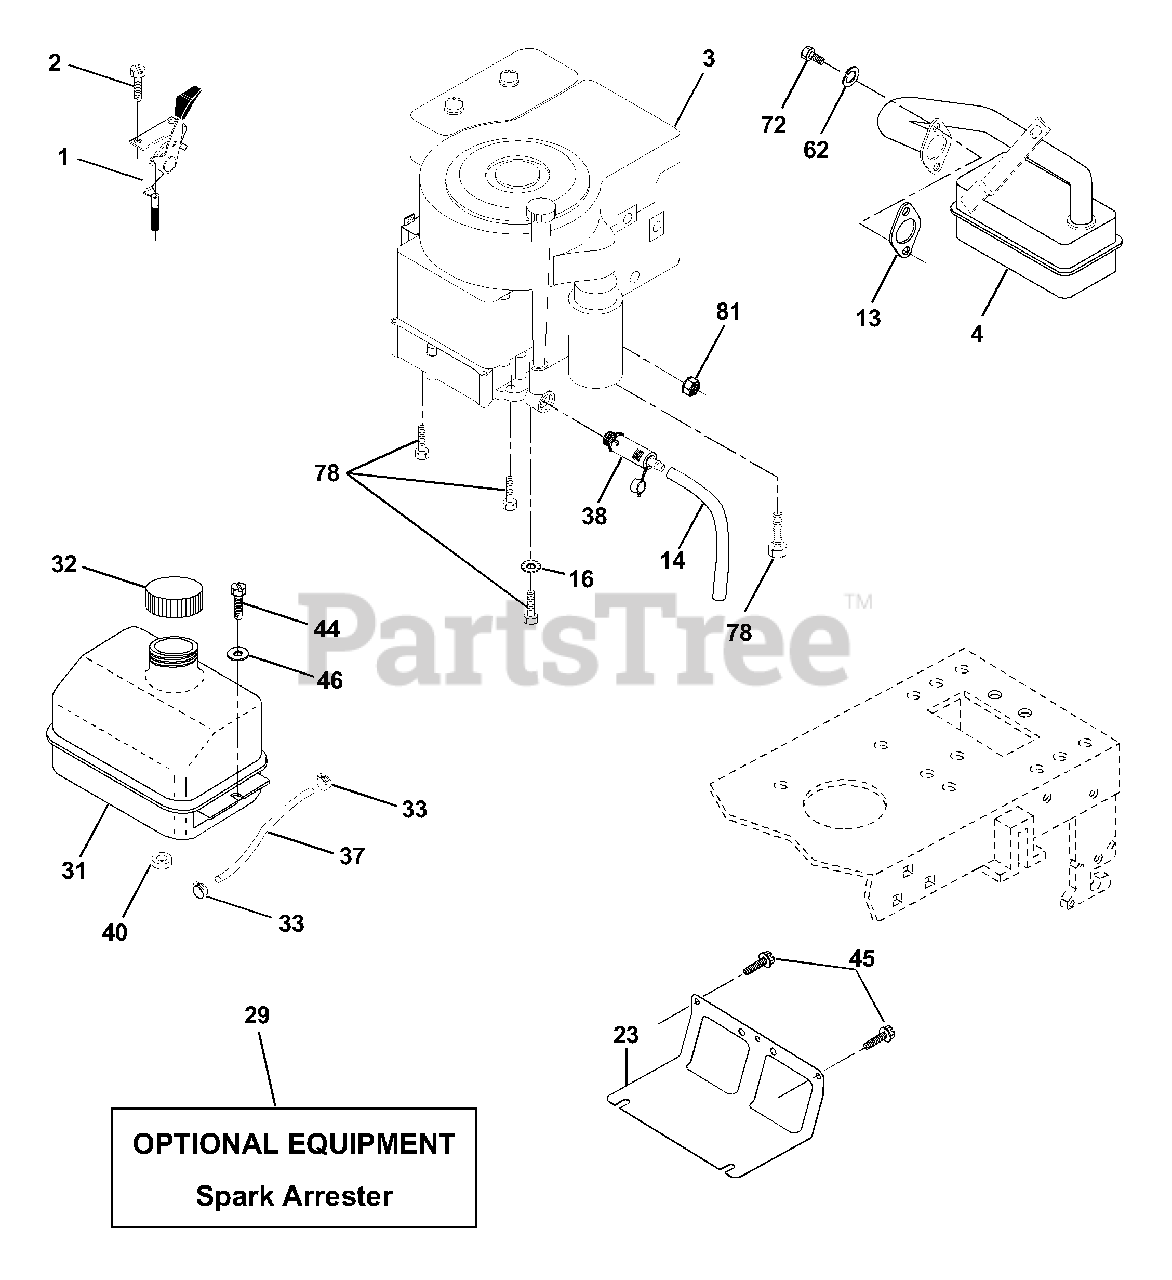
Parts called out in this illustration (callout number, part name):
1	Control Th/ch Flag
2	Screw Hex Thd Cut 1/4-20x5/8 T
4	Muffler LT B&S 12/12.5/13HP
13	Gasket Eng 1 313 Id Tin Plated
14	Tube Drain Oil Easy
16	Washer Lock Ext Tooth 3/8
23	Shield Brn/Dbr Guard
29	Kit Spark Arrestor (Flat Scrn)
31	Tank Fuel Front
32	Cap Asm Fuel W/sym Vented
33	Clamp Hose Black
37	Line Fuel 20"
38	Plug Drain Oil Easy
40	Bushing Snap Nyl Blk Fuel Line
44	Screw Hexwsh Thdrol 1/4-20 x 3/4
45	Screw Hexwsh Thdr 3/8-16 x 3/4
46	Washer 9/32 x 7/8 x 16 Ga
62	Washer Lock Hvy Hlcl Spr 5/16
72	Screw Hexhd Cap 5/16-18 x 3/4
78	Screw 3/8-16 x 1-1/4
81	Nut Keps Hex 1/4-20 Unc
